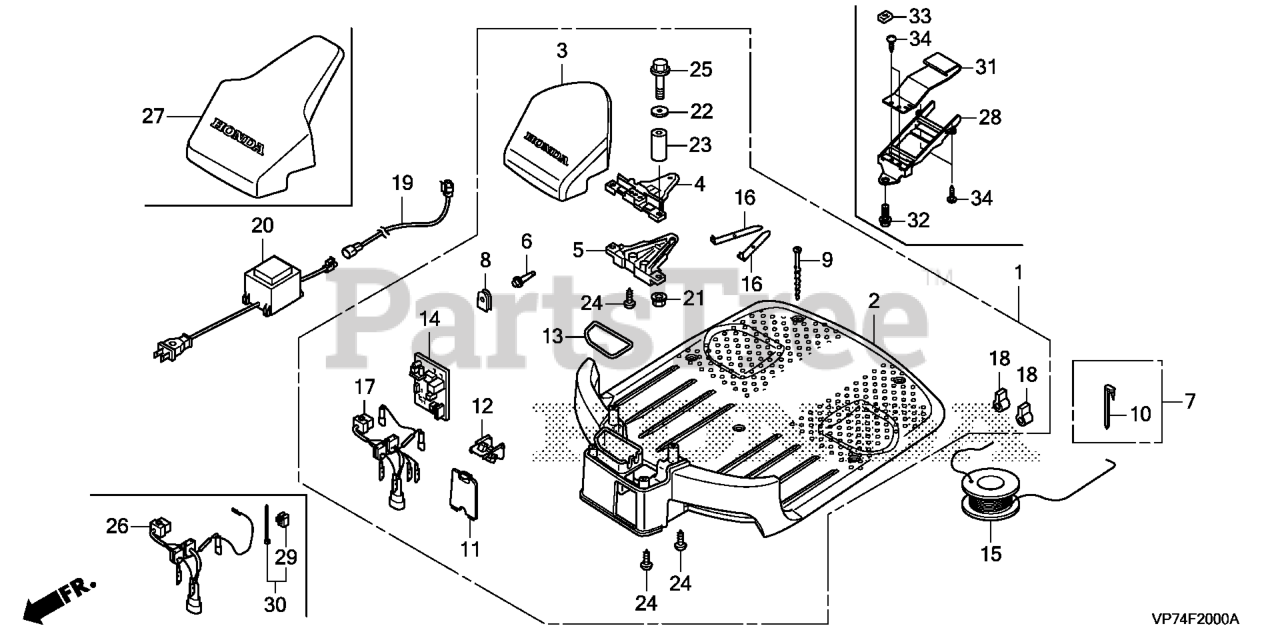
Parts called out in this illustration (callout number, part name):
4	COVER, CHARGE PLUG (UPPER)
5	COVER, CHARGE PLUG (LOWER)
6	LENS, STATION INDICATOR
7	PEG SET, AREA WIRE (50 PIECES)
8	GROMMET, INDICATOR LENS
9	PEG, STATION
10	PEG, AREA WIRE
11	COVER, STATION HARNESS
12	BASE, CONNECTOR
13	SEAL, STATION
14	PCB ASSY., STATION
15	WIRE, AREA (300M) (2.3MM)
15	WIRE, AREA (300M)
16	PLUG, CHARGE
21	NUT, FLANGE (6MM)
22	WASHER, PLAIN (6.5X15)
23	COLLAR, CARRY GRIP
24	SCREW, TAPPING (5X16) (PO)
25	BOLT, FLANGE (6X32)
26	HARNESS ASSY., STATION
27	COVER, STATION
28	BASE, CHARGE PLUG (UPPER)
30	CLIP, BAND
31	PLUG, CHARGE (UPPER)
32	BOLT, FLANGE (6MM)
33	NUT, SPECIAL (6MM)
34	SCREW, TAPPING (4X12)
